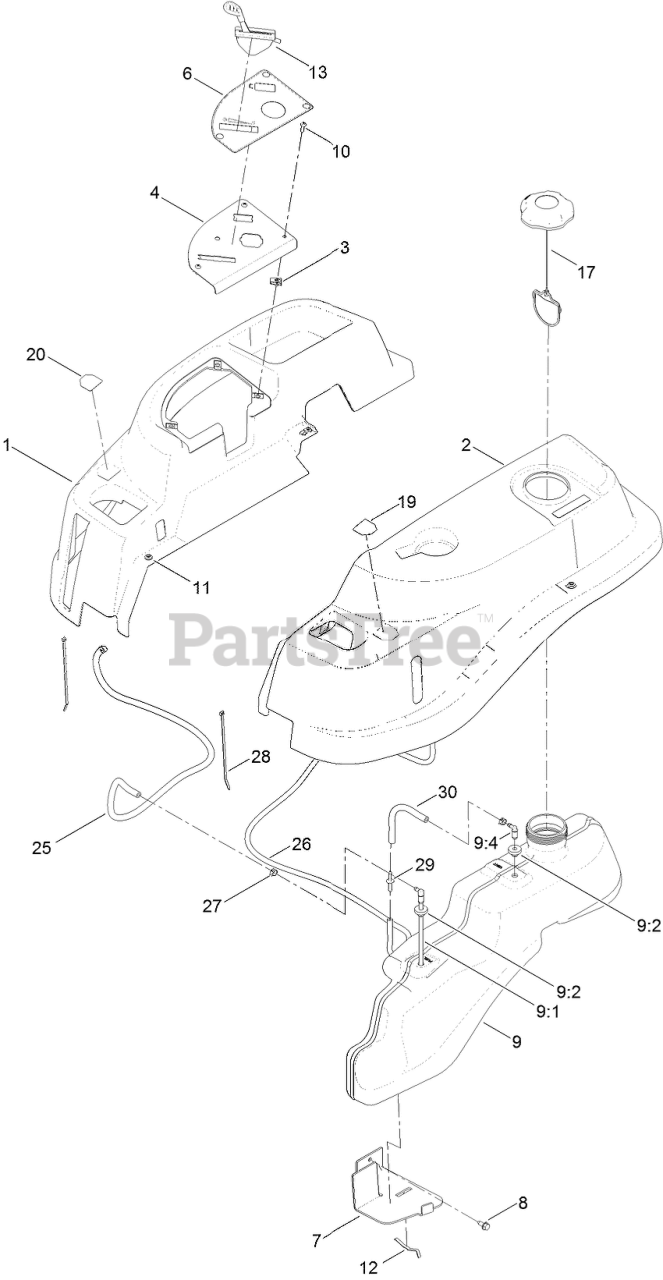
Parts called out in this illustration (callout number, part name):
1	POD-RH
2	POD-LH
4	PLATE-CONTROL
6	DECAL-PANEL, CONTROL
7	SUPPORT-TANK, FRONT
8	SCREW-HWHTF
9	FUEL TANK ASM
9:1	CONNECTOR-ELBOW, 90 DEG
9:2	BUSHING
9:4	FITTING-PLASTIC
10	SCREW-PRH
11	SCREW-SHOULDER
12	SPRING
13	CABLE-THROTTLE
17	CAP-FUEL, RATCHETING
19	DECAL-CONTROL LEVER, LH
20	DECAL-CONTROL LEVER, RH
25	HOSE-FUEL
26	HOSE-FUEL
27	CLAMP-HOSE
28	TIE-CABLE
29	ADAPTOR-ORIFICE
30	HOSE-FUEL
